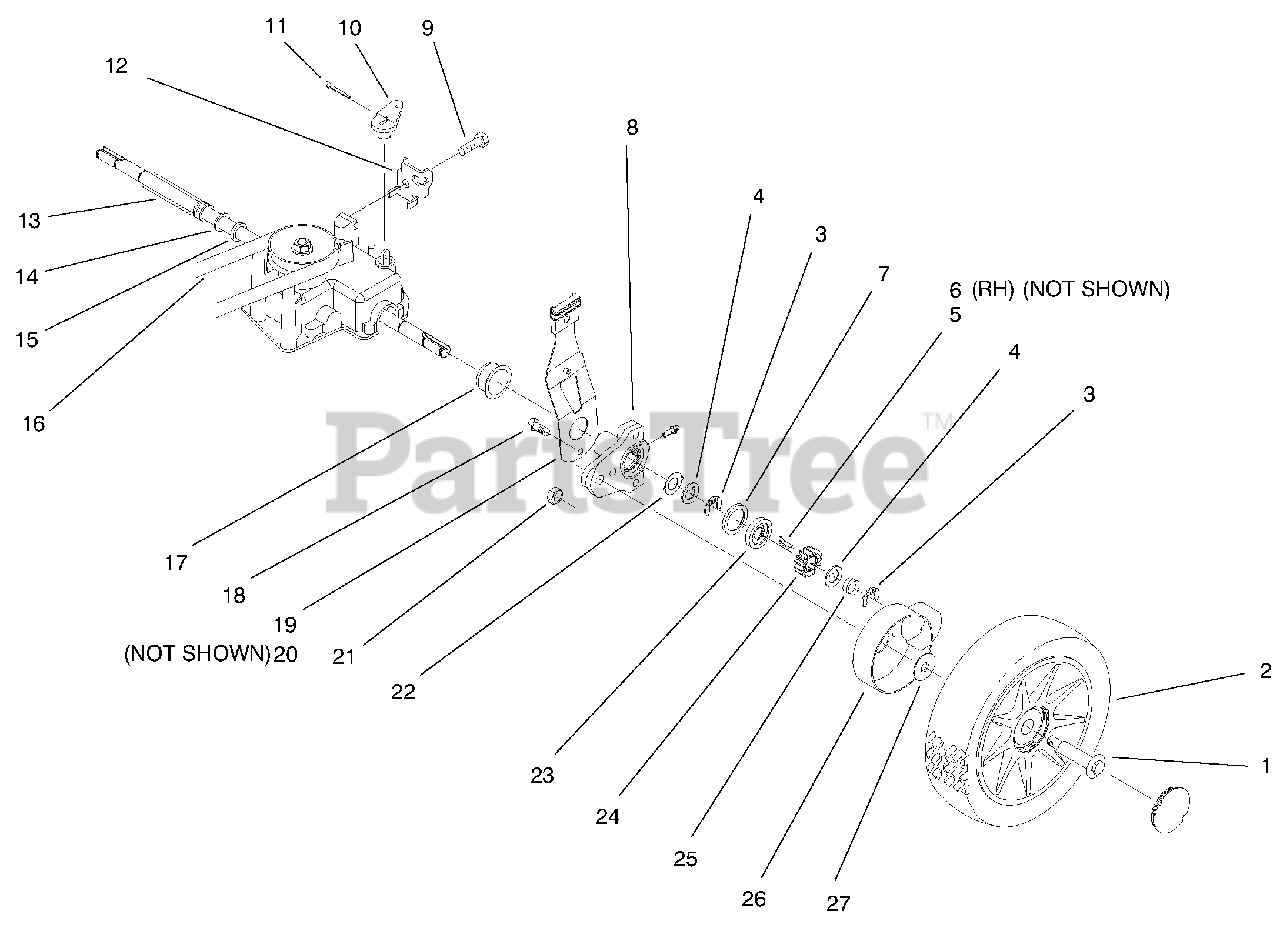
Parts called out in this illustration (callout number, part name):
1	Bolt-Shoulder
3	Ring-Retaining
4	Washer-Thrust
5	Key-Rocking
6	Key-Rocking
7	Ring-Friction
8	ASM-Hgt Adj Arm
9	Screw-TAP
10	Lever-Shift
11	Pin-Cotter
12	Retainer-Cable
13	Cover-Drive Shaft
15	Washer-Flat
19	ASM-Spring Arm
20	ASM-Spring Arm
21	Nut-Lock
22	Washer-Thrust
24	Gear-Pinion
25	Spring-Compression
26	Cover-Wheel
27	Washer-Stepped
